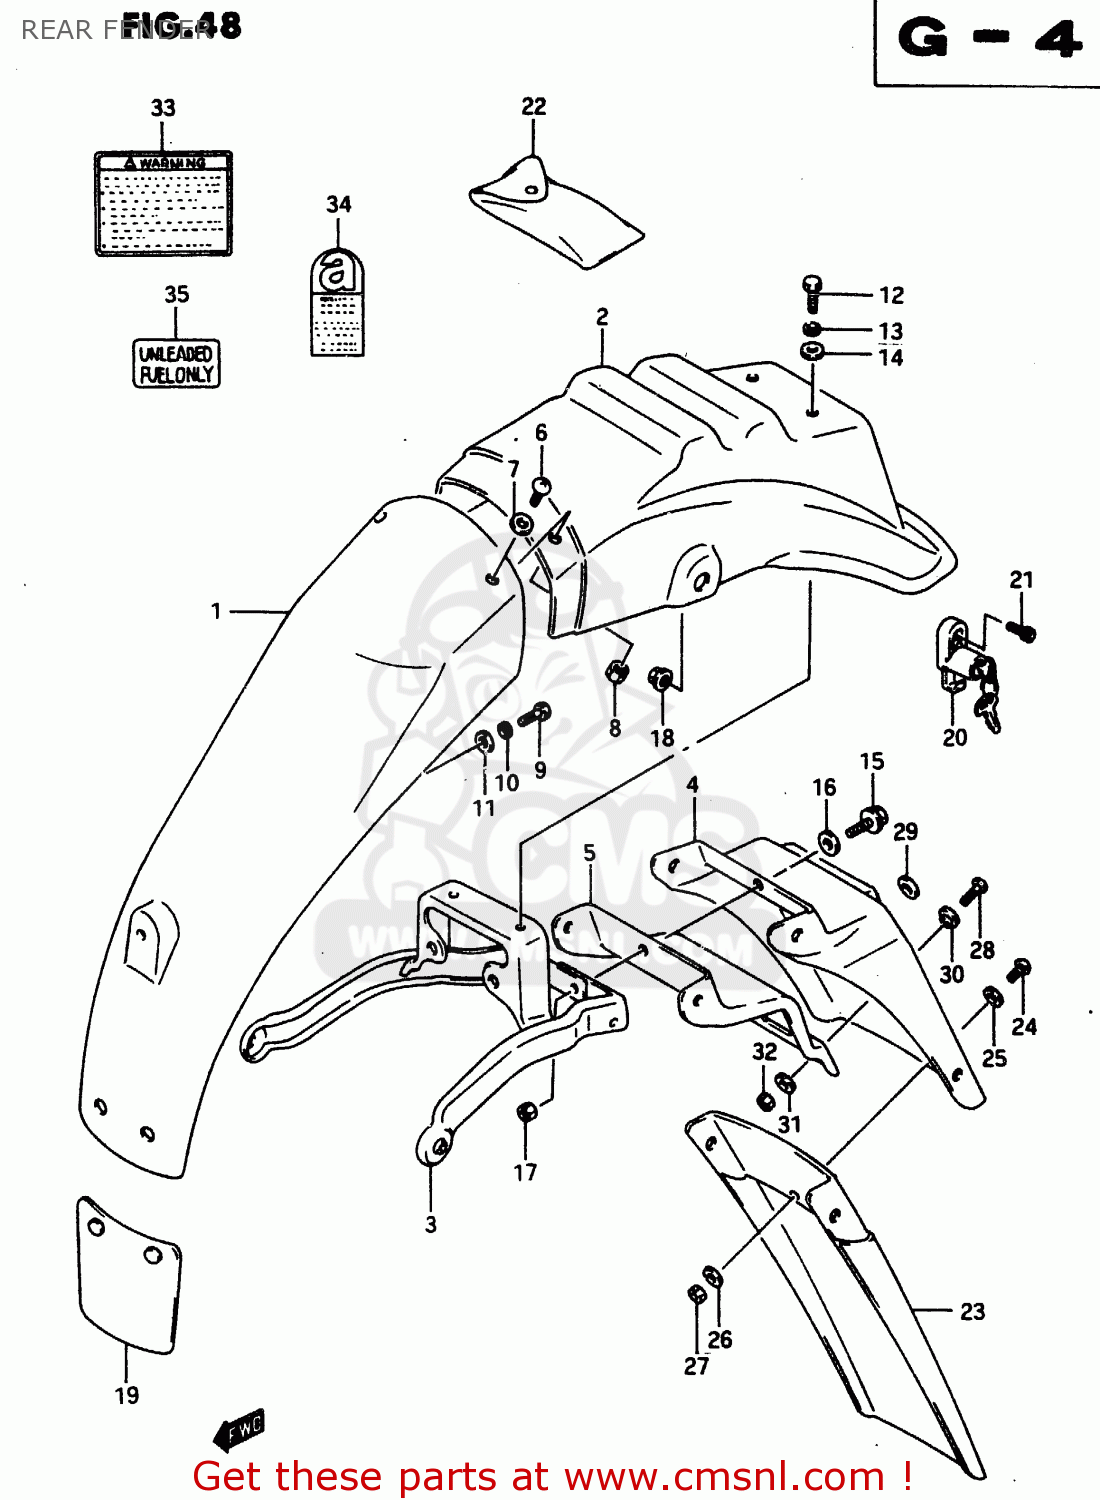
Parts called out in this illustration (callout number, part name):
1	BODY,REAR FENDER,FRONT
2	BODY,REAR FENDER,REAR
3	REINFORCEMENT,REAR FENDER
4	EXTENSION,REAR FENDER
5	REINFORCEMENT,REAR FENDER
6	SCREW, FRONT & REAR
7	WASHER
8	NUT 8MM
9	BOLT 6X16
10	WASHER,LOCK
11	WASHER
12	BOLT
13	WASHER,LOCK
14	WASHER
15	BOLT(6X20)
16	WASHER
17	NUT
18	NUT
19	GUARD,RR FENDER FR MUD
20	LOCK SET,HELMET
21	BOLT
22	TOOL ASSY
23	MUD GUARD
24	SCREW 6X12
25	WASHER(6.5X16X1.2)
26	WASHER,LOCK
27	NUT
28	SCREW
29	WASHER
30	WASHER
31	WASHER
32	NUT
33	LABEL
34	LABEL,ASBESTOS WARNING
35	LABEL,FUEL CAUTION
